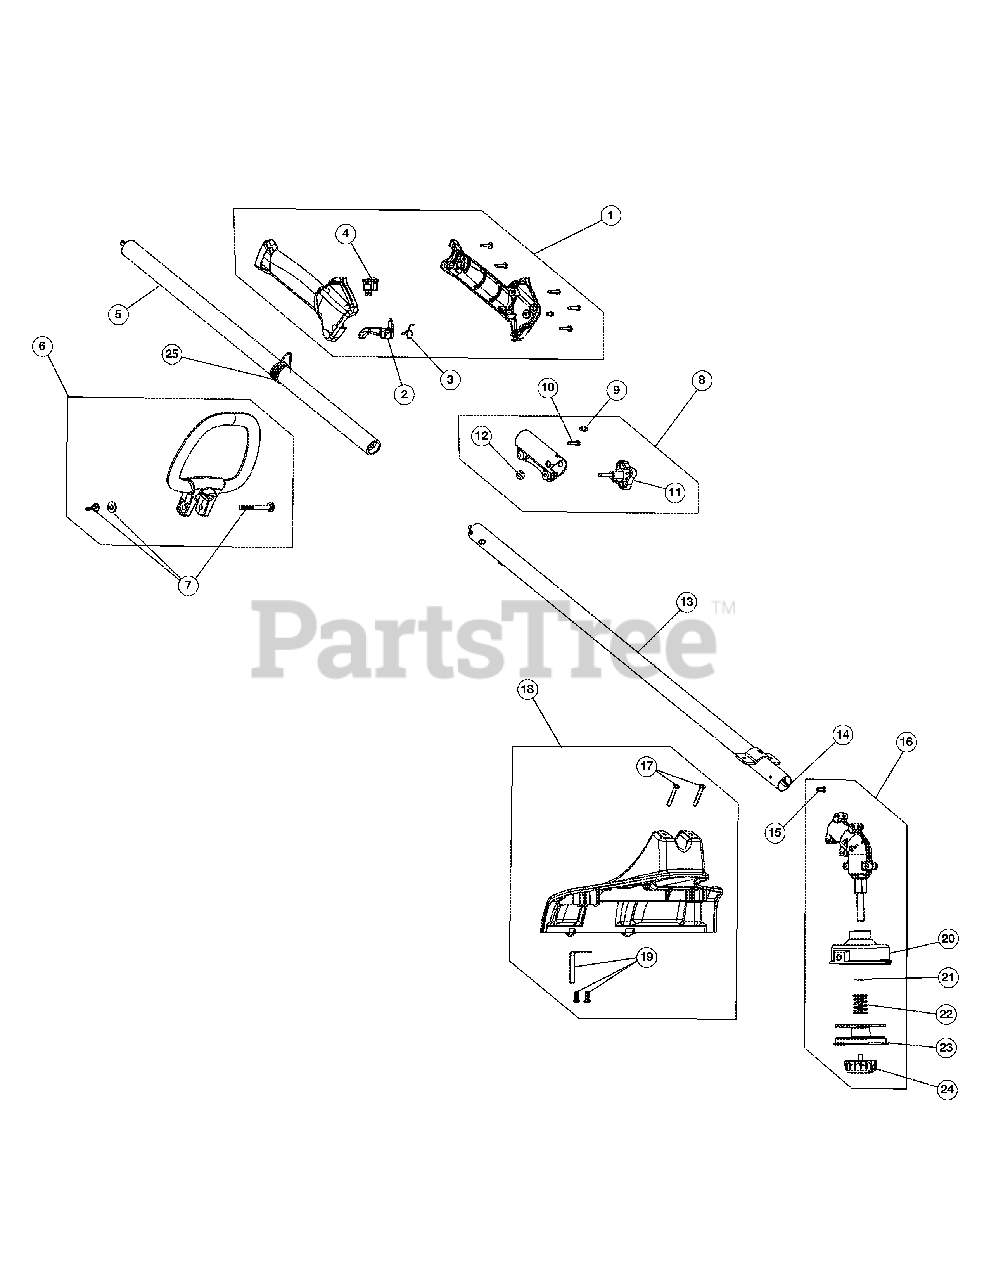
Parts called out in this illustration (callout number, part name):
1	Throttle Housing Assembly (Incl. Ref No. 2-4)
2	Throttle Trigger
3	Throttle Trigger Spring
5	Upper Drive Shaft Housing Assembly
6	Handle Assembly (Incl. Ref No. 7)
7	Handle Hardware
8	Split Boom Coupler (Incl. Ref No. 9-12)
11	Adjustment Knob (Incl. Ref No. 12)
12	Knob Retaining Nut
13	Lower Drive Shaft Housing Assembly
14	Lower Flexible Drive Shaft
15	Anti-Rotation Screw
16	Gear Box Assembly (Incl. Ref No. 15 & 20-24)
17	Shield Mounting Screws
18	Shield Assembly (Incl. Ref No. 17 & 19)
19	Blade Assembly
20	Outer Spool Assembly
21	Retainer
23	Inner Reel
24	Bump Knob Assembly
25	Shoulder Strap Clip
